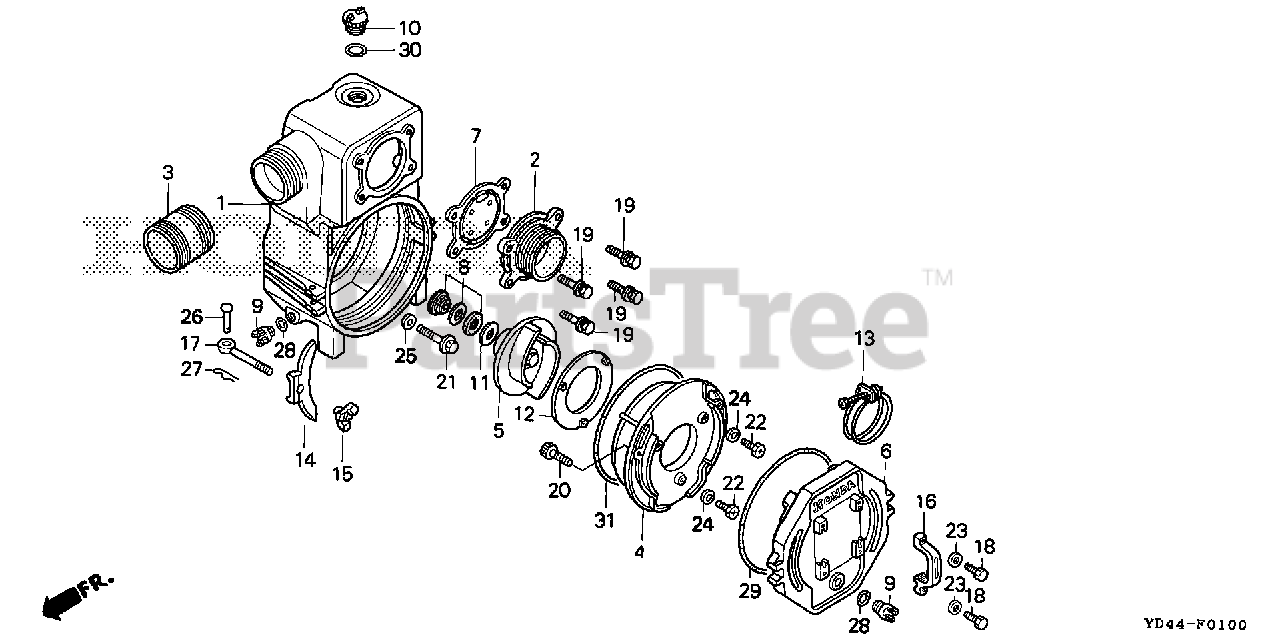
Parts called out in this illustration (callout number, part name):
4	CASE, VOLUTE
6	COVER, DRAIN
7	VALVE, IN.
8	SEAL ASSY., MECHANICAL
9	CAP, DRAIN
10	CAP, FILLER
11	SHIM, ADJUSTER
13	BAND, HOSE
14	HOLDER, DRAIN COVER
15	KNOB, DRAIN COVER
16	HANDLE, DRAIN COVER
17	BOLT, DRAIN COVER
18	BOLT, HANDLE SETTING
19	BOLT-WASHER (10X30)
20	BOLT-WASHER, SOCKET (8X25)
21	BOLT, CASING SETTING
22	BOLT, LINER SETTING (5X14)
23	WASHER, PLAIN (6MM)
24	WASHER, SPRING (5MM)
25	WASHER, SEAL
26	PIN, HINGE
28	O-RING (3.5X23.7)
29	O-RING (5.7X239.3)
30	O-RING (3.5X29.7)
31	O-RING (3.53X215.49)
